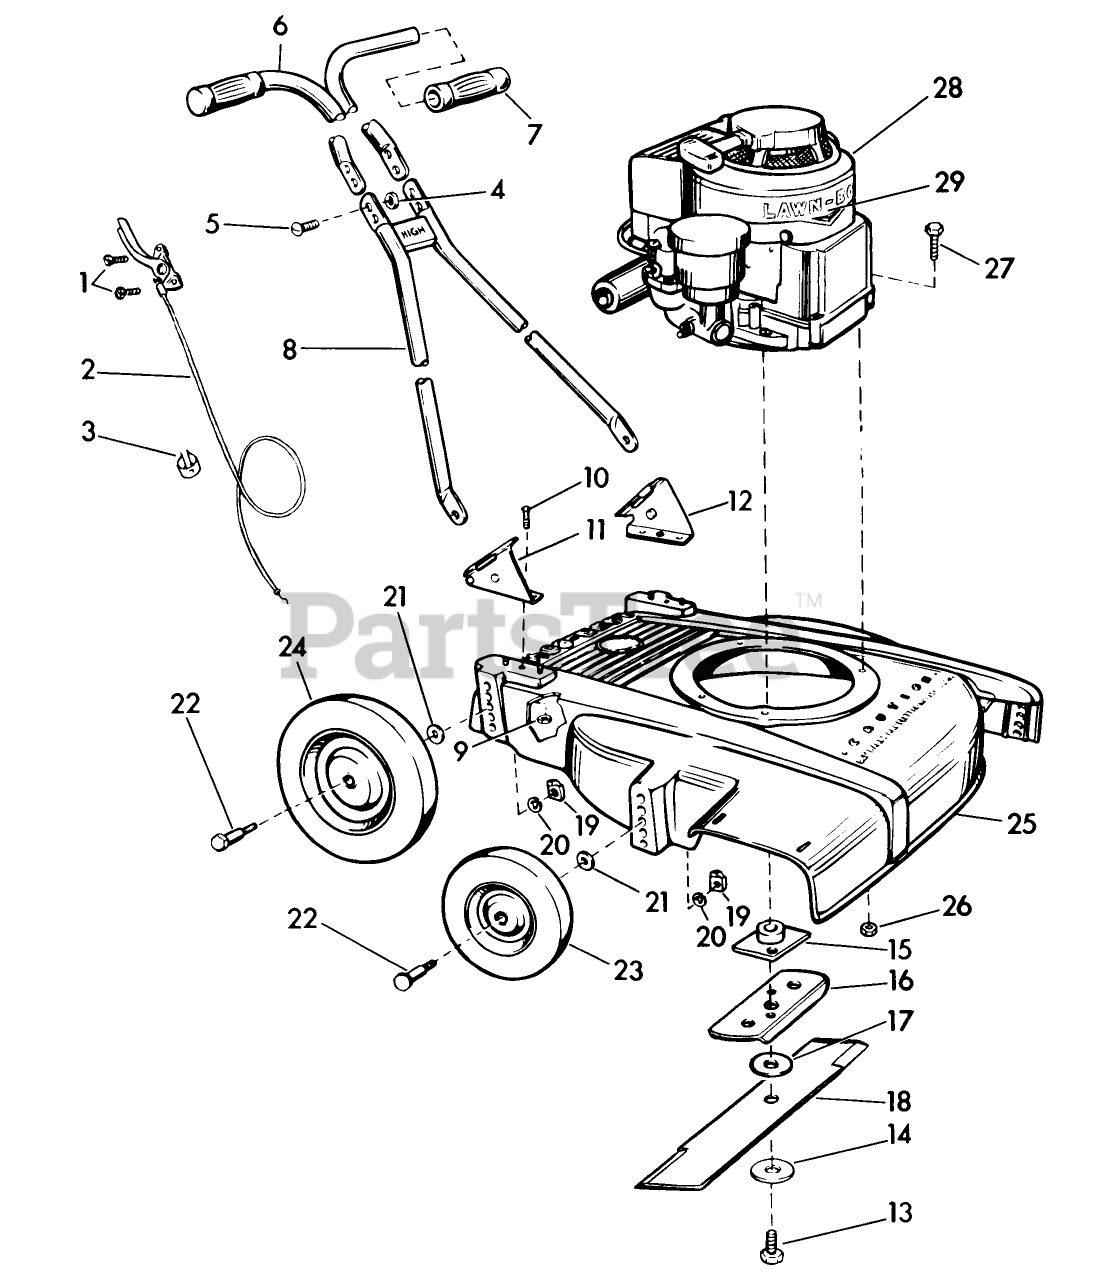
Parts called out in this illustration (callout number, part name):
3	Clip-Control Cable
4	STOP NUT
13	Stud-Blade Mounting
14	Washer-Blade Mounting
15	PLATE AND COLLAR ASM
16	Stiffener-Blade
18	Blade-18"
18	Blade-21"
20	WASHER, LOCK
25	Housing-18"
25	Housing-21"
28	Engine-Model 6B-H, Briggs and Stratton
